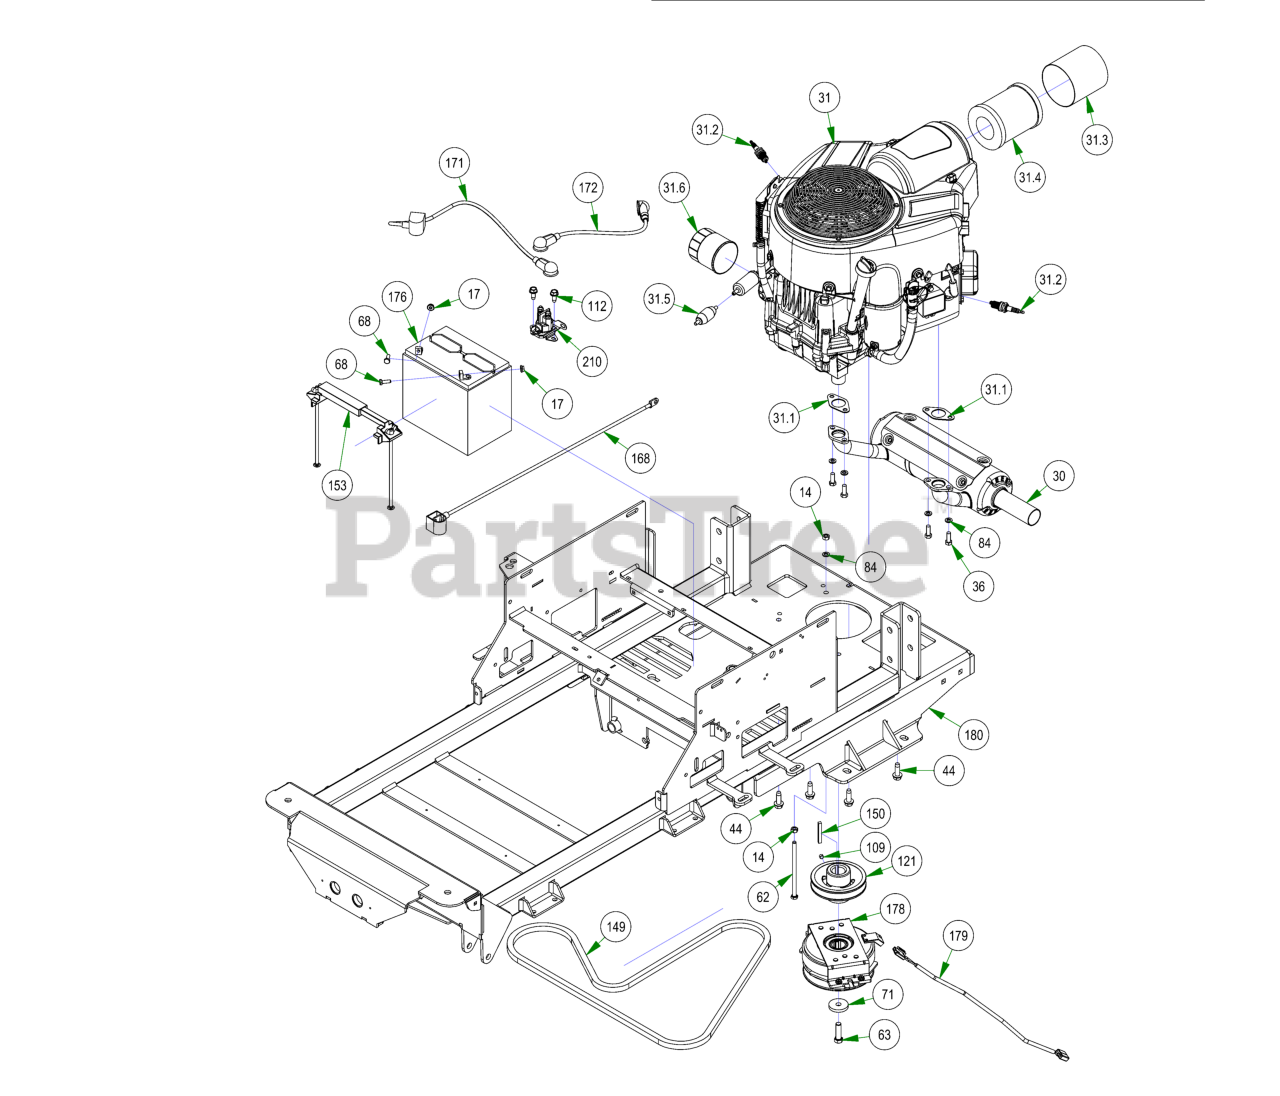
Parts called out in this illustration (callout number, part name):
14	5/16-18 HEX NUT ZINC
17	1/4-20 HEX SERRATED FLANGE NUT HARD/ZINC
30	2017 Compact Outlaw Exhaust 810 Vanguard
31	Vanguard 27hp CXI with Out Oil Filter Maverick
31.1	Exhaust Gasket
31.2	Spark Plug
31.3	pre-Cleaner for Vanguard CXI Engine
31.4	Air Filter for Vanguard CXI Engine
31.5	Universal Inline Fuel Filter
31.6	Oil Filter
36	Torx Bolt-Exhaust
44	3/8-16 X 1-1/8 HEX WASHER UNSLOT SERRATED (TRI-LOB) TRS ZINC YELLOW
62	5/16-18 X 5-1/2 HEX CAP SCREW (GR.5) ZINC
63	7/16-20 X 1-1/2 HEX CAP SCREW (GR.8) w/ Patch
68	1/4-20 X 3/4 HEX CAP SCREW (GR.5) ZINC
71	CLUTCH WASHER
84	5/16 SPLIT LOCKWASHER ZINC
109	5/16-24 X 1/4 SOCKET SET SCREW (CUP PT) PLAIN
112	5/16-18 X 3/4 HEX WASHER SLOT (F) TCS ZINC
121	4 3/4 Motor Pulley
149	75.8" Pump Belt
150	1/4 X 2 SQ MACHINERY KEY 1018 STL PLAIN
153	Hold Down Assembly
168	24 inch Black Cable – MZ/ZT
171	24" Red Battery Cable
172	12" Red Battery Cable
176	SP-35 Battery
179	Clutch Pigtail
180	2022 Maverick Frame - Painted
